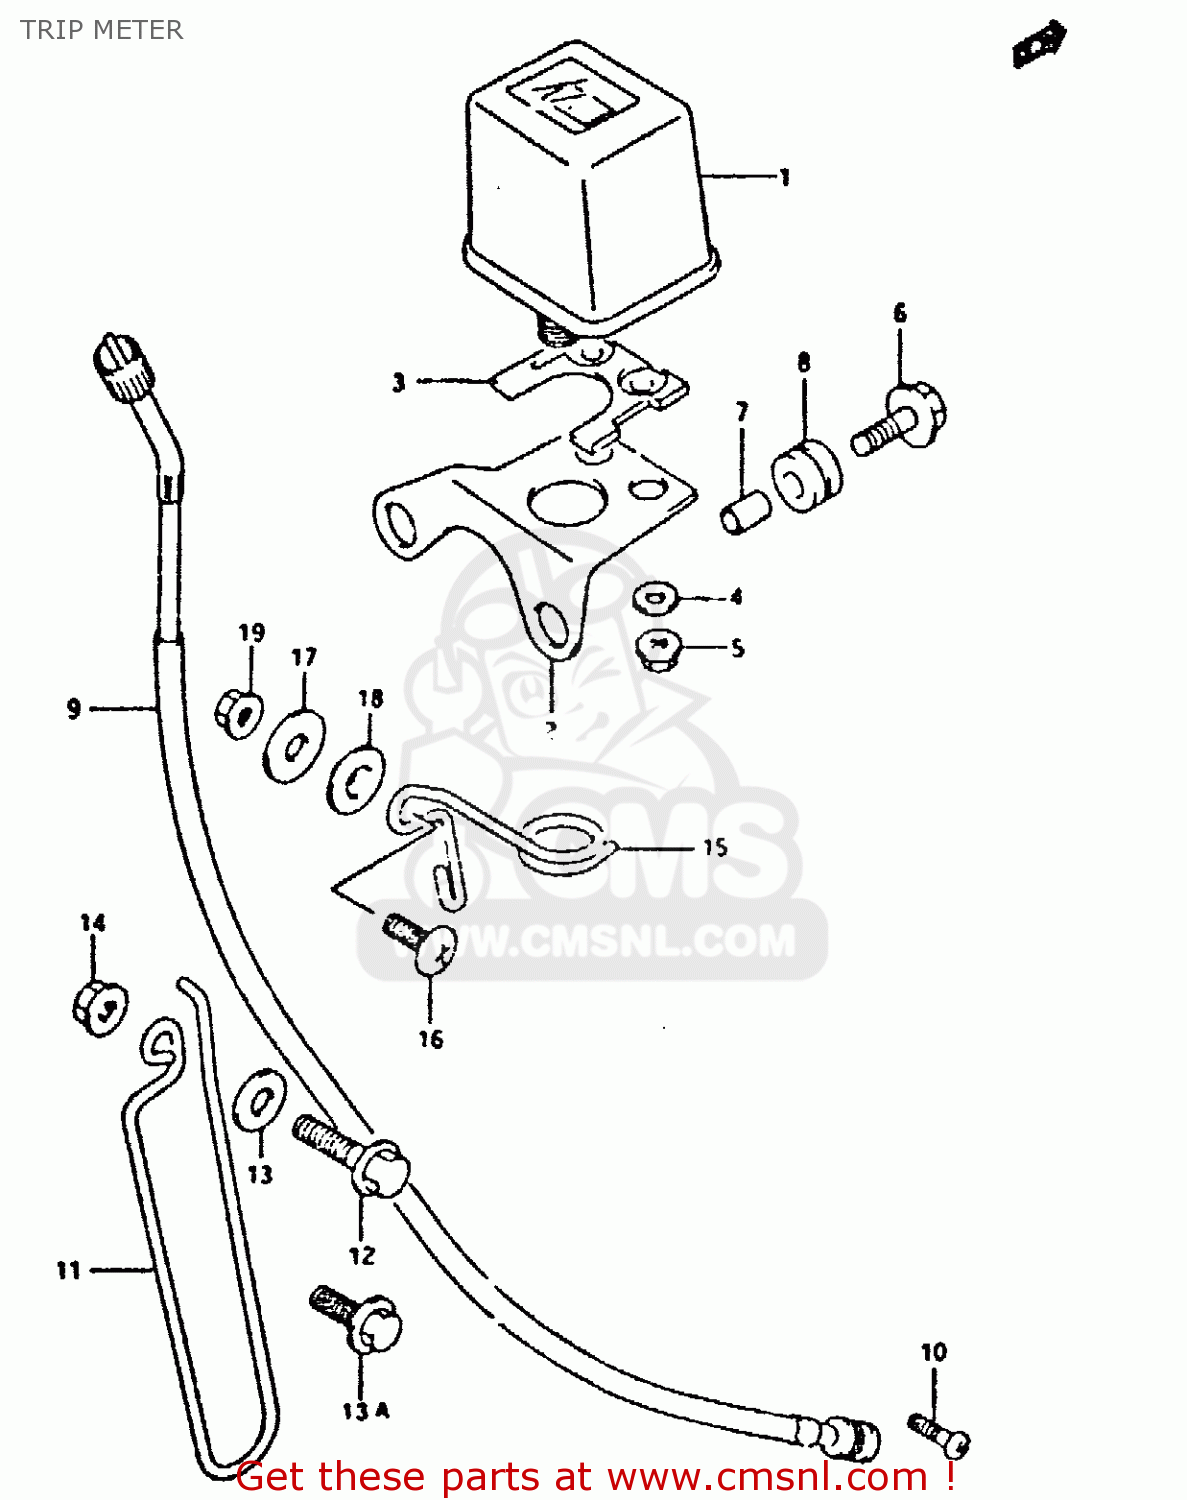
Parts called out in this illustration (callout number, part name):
1	TRIP METER
2	BRACKET
3	CUSHION
4	WASHER,METER
5	NUT
6	BOLT(6X25)
7	SPACER (6.1X8X9.5)
8	CUSHION
9	CABLE ASSY,SPEEDOMETER
10	SCREW
11	GUIDE,METER CABLE NO.2
12	BOLT
13	WASHER(6.5X20X1.6)
13A	BOLT(6X20)
14	NUT
15	GUIDE,METER CABLE NO.3
16	SCREW
17	WASHER
18	WASHER
19	NUT
